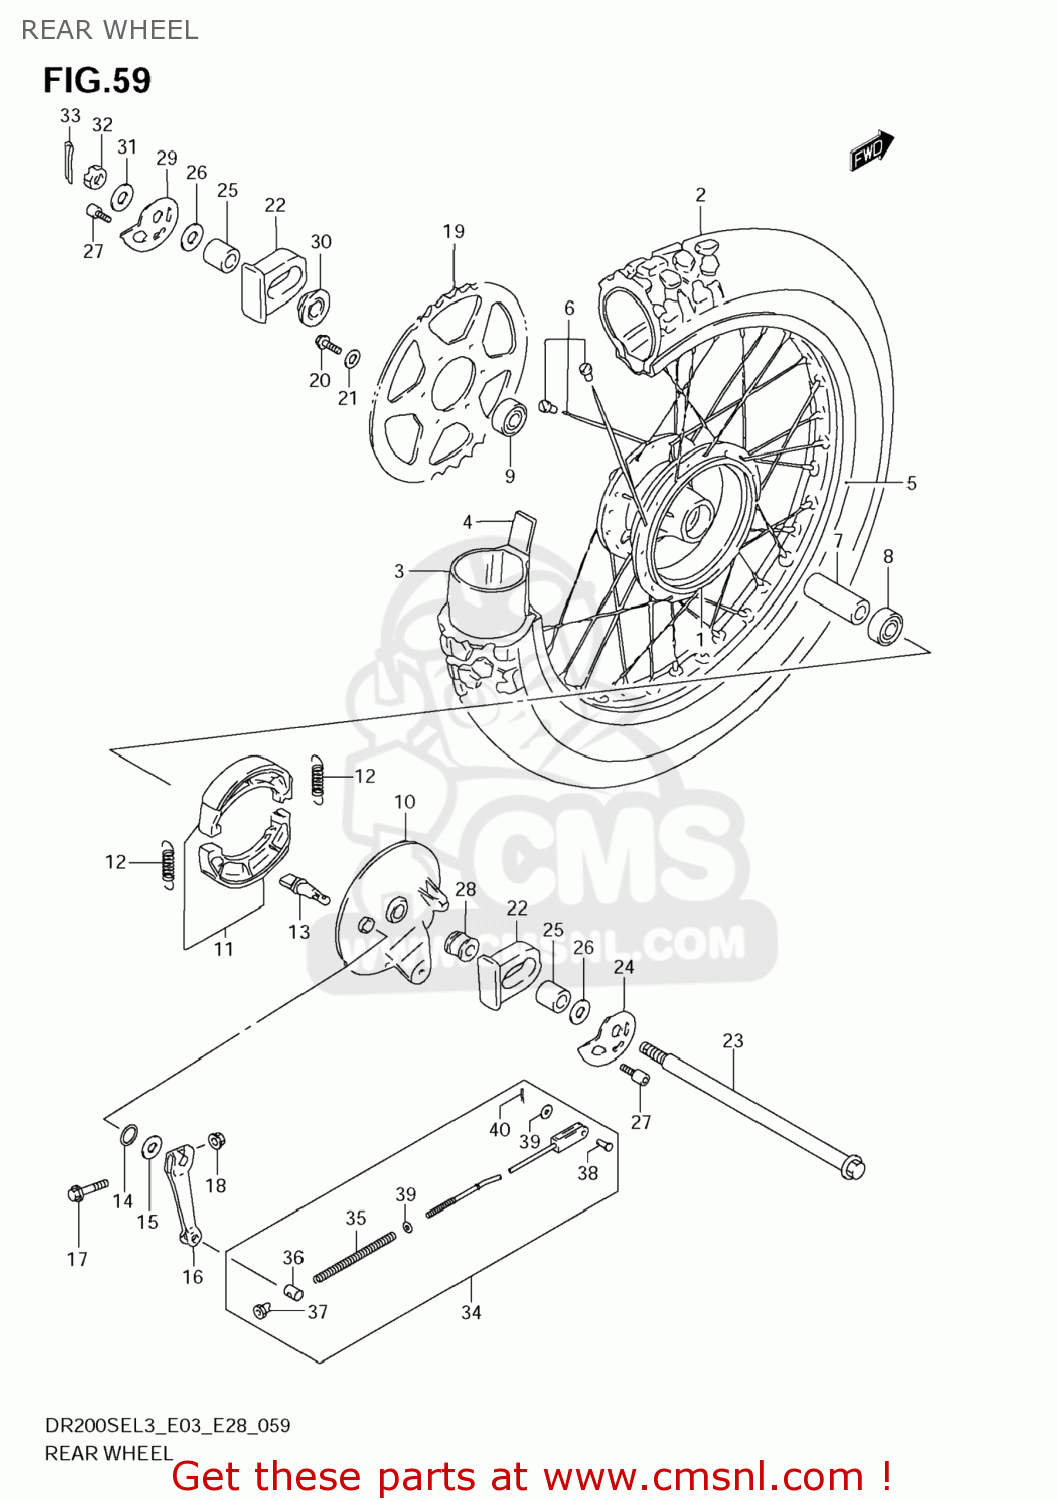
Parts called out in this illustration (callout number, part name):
1	HUB,RR WHEEL
2	TIRE,RR(100/90-18 56P)
3	TUBE ASSY,WHEEL INNER
4	PROTECTOR,WHL INR TUBE
5	RIM,RR WHEEL(18X2.15 AL)
6	SPOKE ASSY,RR WHEEL
7	SPACER(15.3X21.7X107.5)
8	BEARING
9	BEARING
10	PANEL,RR BRAKE ANCHOR
11	SHOE SET,BRAKE (NAS)
12	SPRING(L:34)
13	CAM,BRAKE
14	O RING(D:2.5,ID:13.8)
15	WASHER(14.5X22X1.6)
16	LEVER,RR BRAKE CAM
17	BOLT
18	NUT
19	SPROCKET,RR(NT:45)
20	BOLT(8X30)
21	WASHER
22	CAP,RR SWINGING ARM
23	AXLE,RR
24	ADJUSTER,CHAIN,R
25	SPACER,CHAIN ADJUSTER
26	WASHER(15.5X30X3.2)
27	BOLT,CHAIN ADJUSTER
28	SPACER,RR AXLE,R
29	ADJUSTER,CHAIN,L
30	SPACER,RR AXLE,L
31	WASHER(14.5X30X3.2)
32	NUT
33	PIN
34	ROD ASSY,RR BRAKE
35	SPRING
36	PIN(13X18)
37	NUT
38	PIN(L:13.5)
39	WASHER
40	PIN
